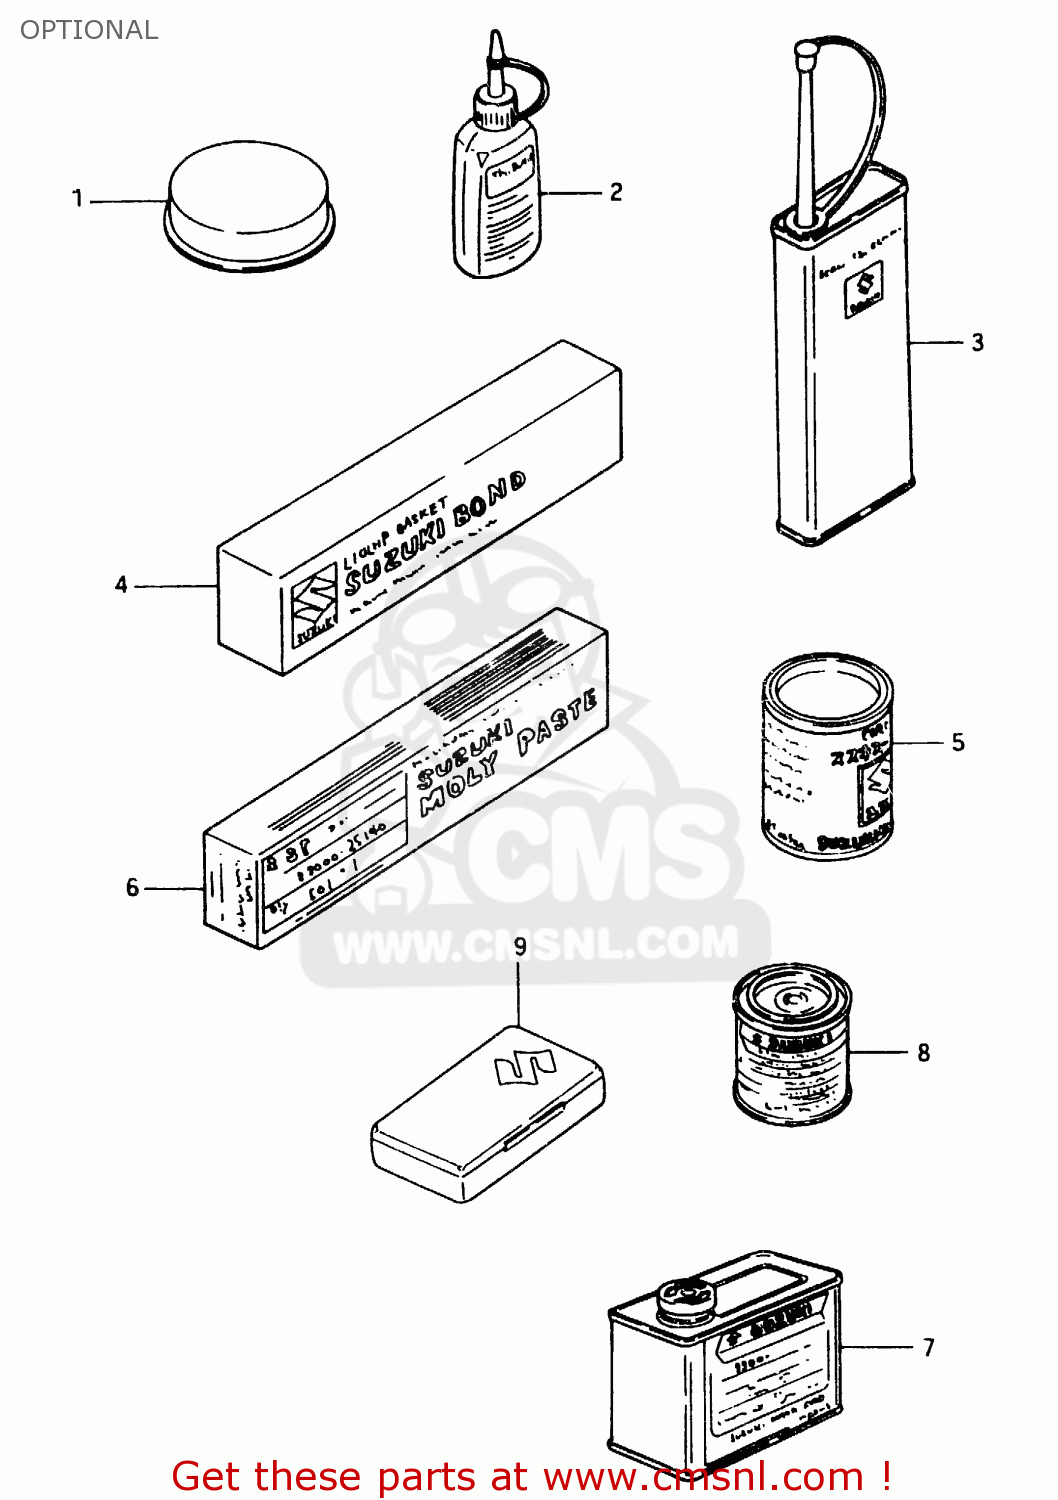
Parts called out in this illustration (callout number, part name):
1	GREASE,PBC FOR BRK PAD 20G
2	THREAD LOCK NO.1342
3	THREAD LOCK NO.1401 CLEAR 200G
4	LIQUID GSKT NO.1207B 100G BLK
5	GREASE(C)EP2 LITHIUM 150G
6	SUZUKI MOLY PASTE
7	PAINT (BLACK)
8	PAINT,BLACK
9	TUBE REPARING TOOL
